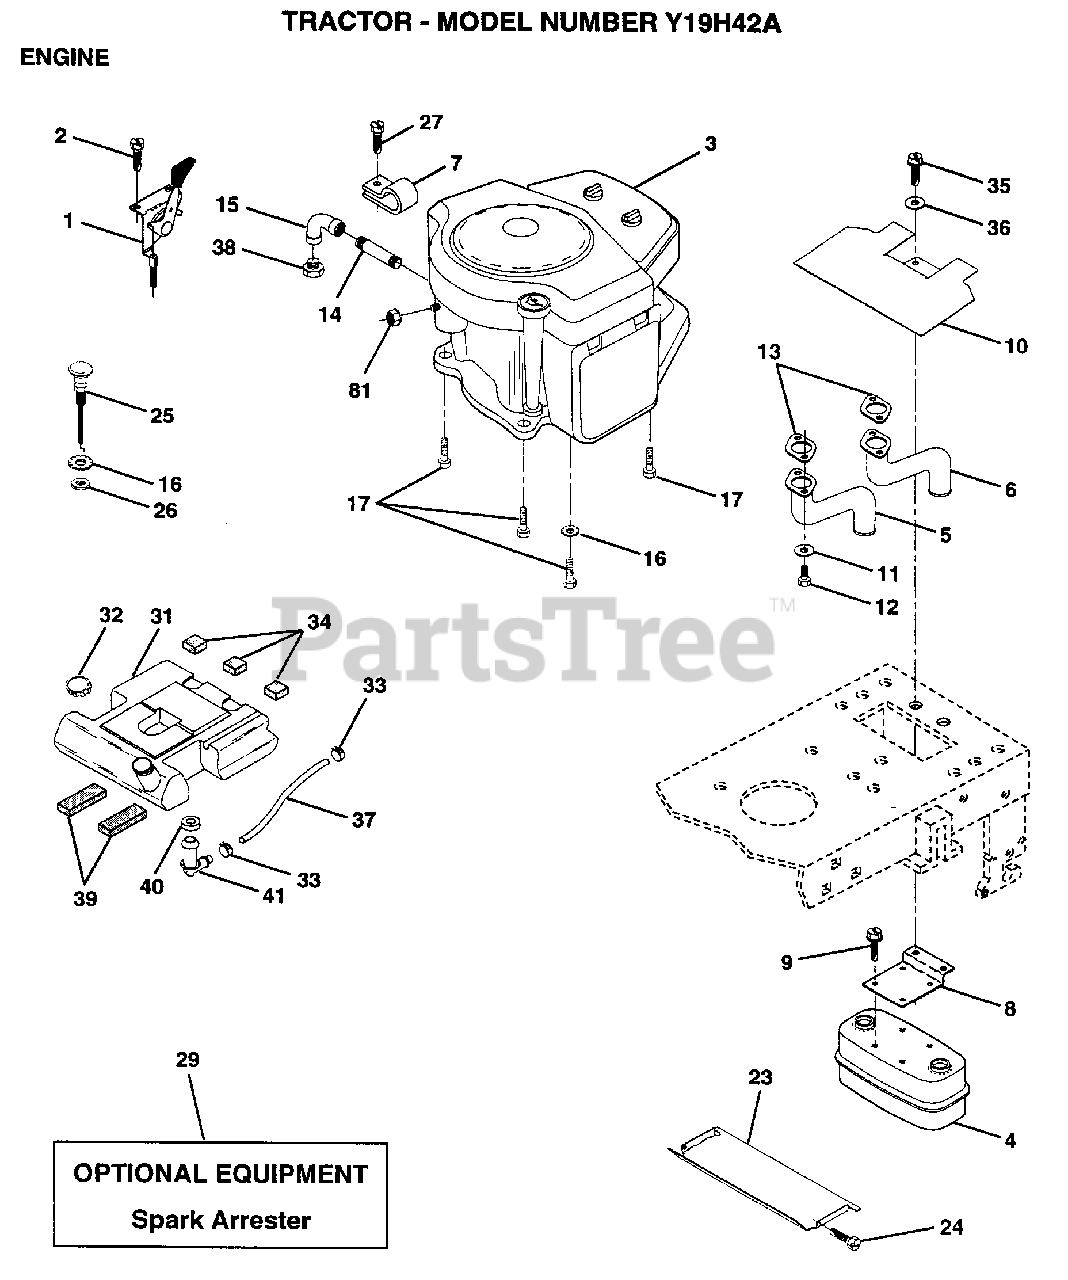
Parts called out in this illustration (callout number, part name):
2	DRAWBAR GT
4	NUT.7/16
5	DASHBOARD BLACK
6	DASH.1PC.LOWER
7	SCREW
8	SUPPORT.DASH.BTRY
9	PAL NUT LT
14	No Desciption for Part
15	LENS.BAR.CLEAR
16	COVER ACCESS
17	SCREW
19	WASHER
22	PANEL SIDE RH
24	Footrest
26	SCREW
28	FOOTREST.LH.LT/GT *SUBS/2*
29	DASH.SUPT.YP/HUSQ
30	SADDLE.HYDRO.95
31	BRAKET.SUPT.STEER
32	BRACKET ASM FRAME
33	BRACKET ASM FRAME
34	BRACKET.ENG.SUPT.
35	WASHER
36	BOLT
37	FENDER.PNT.
38	LOCKWASHER
39	BRACKET.AXLE.FRT.
43	BRACKET.SUS.FT.LH
44	BRACKET.SUS.FT.RH
46	WASHER PM
47	SCREW LT
50	BRACKET.CHASSIS.
51	SCREW CRT
57	NUT HXKEP 1/4X20
58	BRKT.ASM.FENDER
60	SCREW
63	WASHER
68	SCREW LT
69	SHIELD.HEAT.MUF
70	GUIDE.BELT.MID.SP
71	STRAP.GRILLE.PNT.
72	SCREW
74	SCREW
75	LOCKWASHER
76	WELDNUT
79	SCREW
80	SPACER LT
81	WASHER
84	STOP.OVER.CENTER
86	BOLT
90	LOCKWASHER
92	PLATE YP SLKSCR
94	CLIP GTV
95	NUT-PUSH YT
98	NUT-PUSH YT
98	BRACKET SKID CHAS
99	ROD BYPASS
100	CAP
101	SCREW LT
102	RETAINER M (5 2)(3 2)
103	LOCK BYPASS BRKT
107	HOOD LATCH T
114	BOLT.3/8-14X1.25
115	BUMPER.ASM.W/PY
116	BRACKET.EXT.BUMP.
117	PLUG.PLASTIC
118	WASHER
120	WASHER HYT
124	NUT
